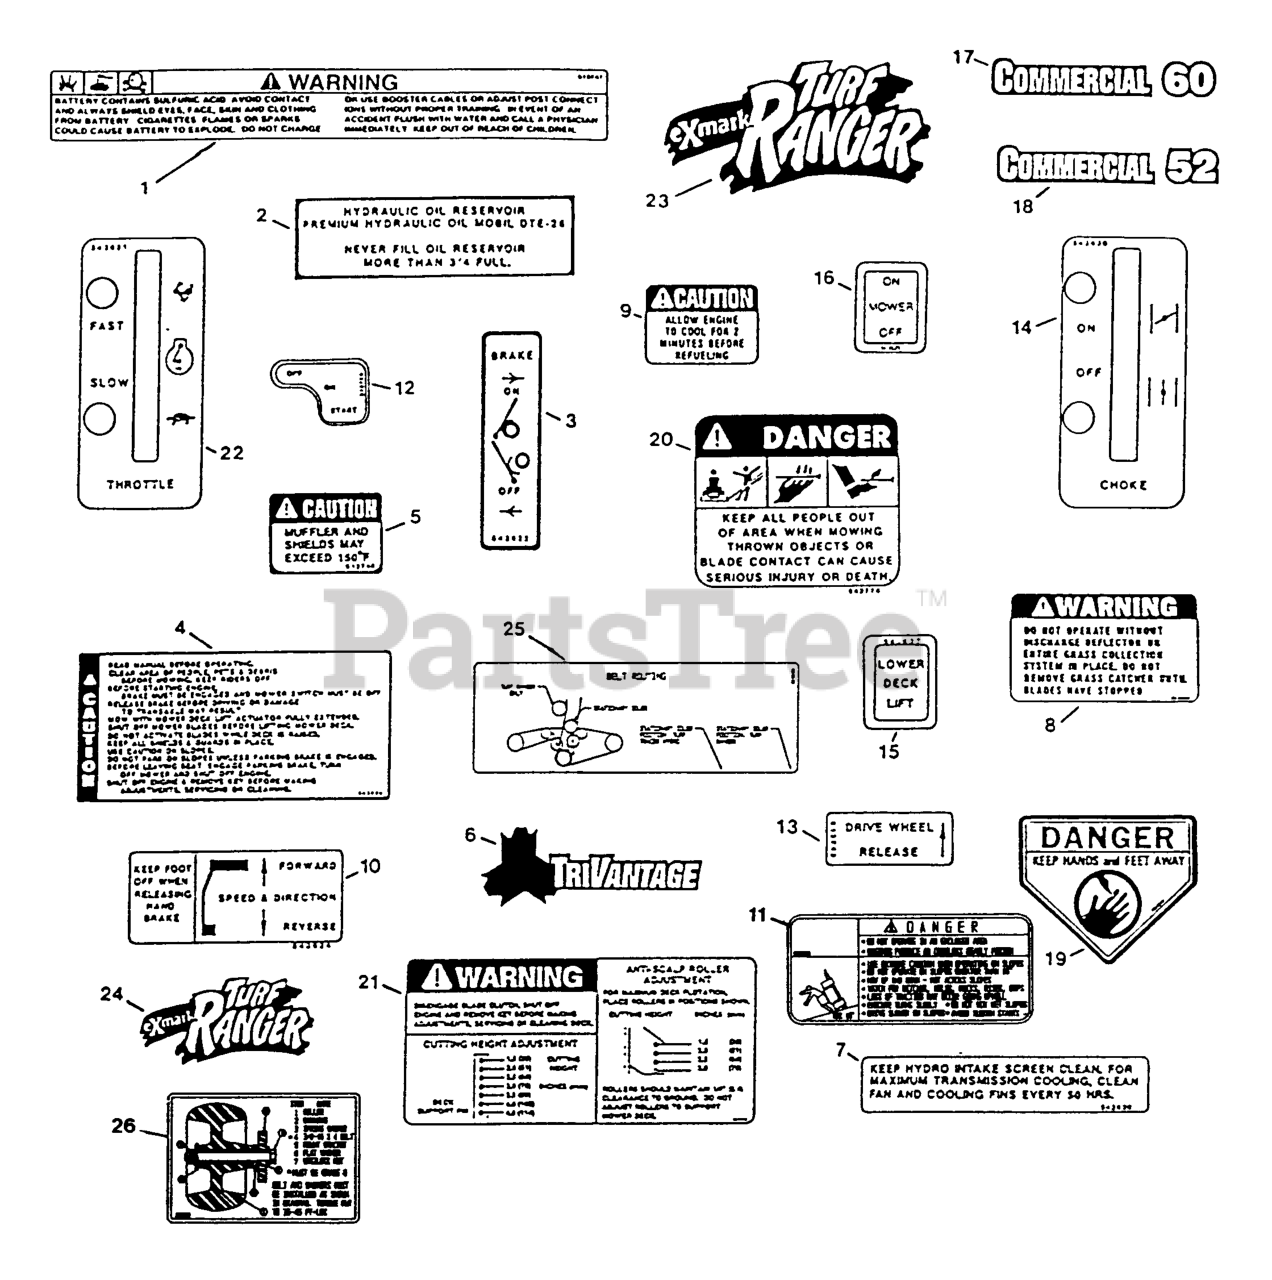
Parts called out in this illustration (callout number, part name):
1	DECAL-BATTERY
7	DECAL,INTAKE
8	DECAL-WARNING, DISCHARGE
10	DECAL,FOOT PEDAL
11	DECAL,DANGER
15	DECAL-DECK LIFT
16	DECAL-MOWER SWITCH
17	DECAL,COMMERCIAL 60
18	DECAL,COMMERCIAL 52
19	DECAL-DANGER
20	DECAL-DANGER
23	DECAL,SWASH RANGER
25	DECAL,BELT ROUTING
26	DECAL,ROLLER MOUNTING
